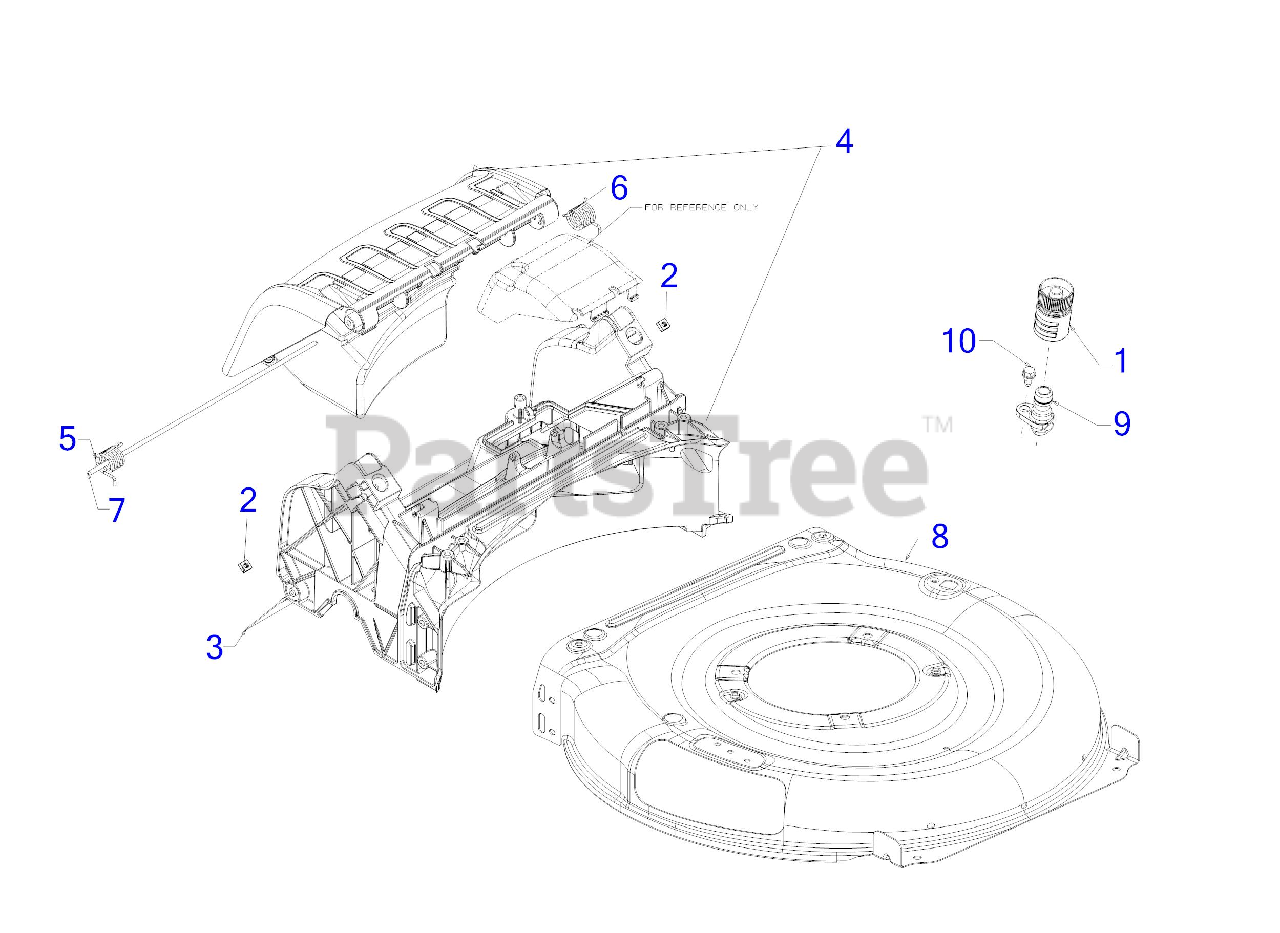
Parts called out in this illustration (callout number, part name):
1	WATER NOZZLE
2	SQUARE NUT 1/4-20
3	TRAILSHIELD
4	REAR BAG BAFFLE ASSEMBLY
5	TORSION SPRING (RH)
6	TORSION SPRING (LH)
7	REAR DOOR PIVOT ROD
9	DECK WASH NOZZLE
10	SHOULDER SCREW 1/4-20 x .50
